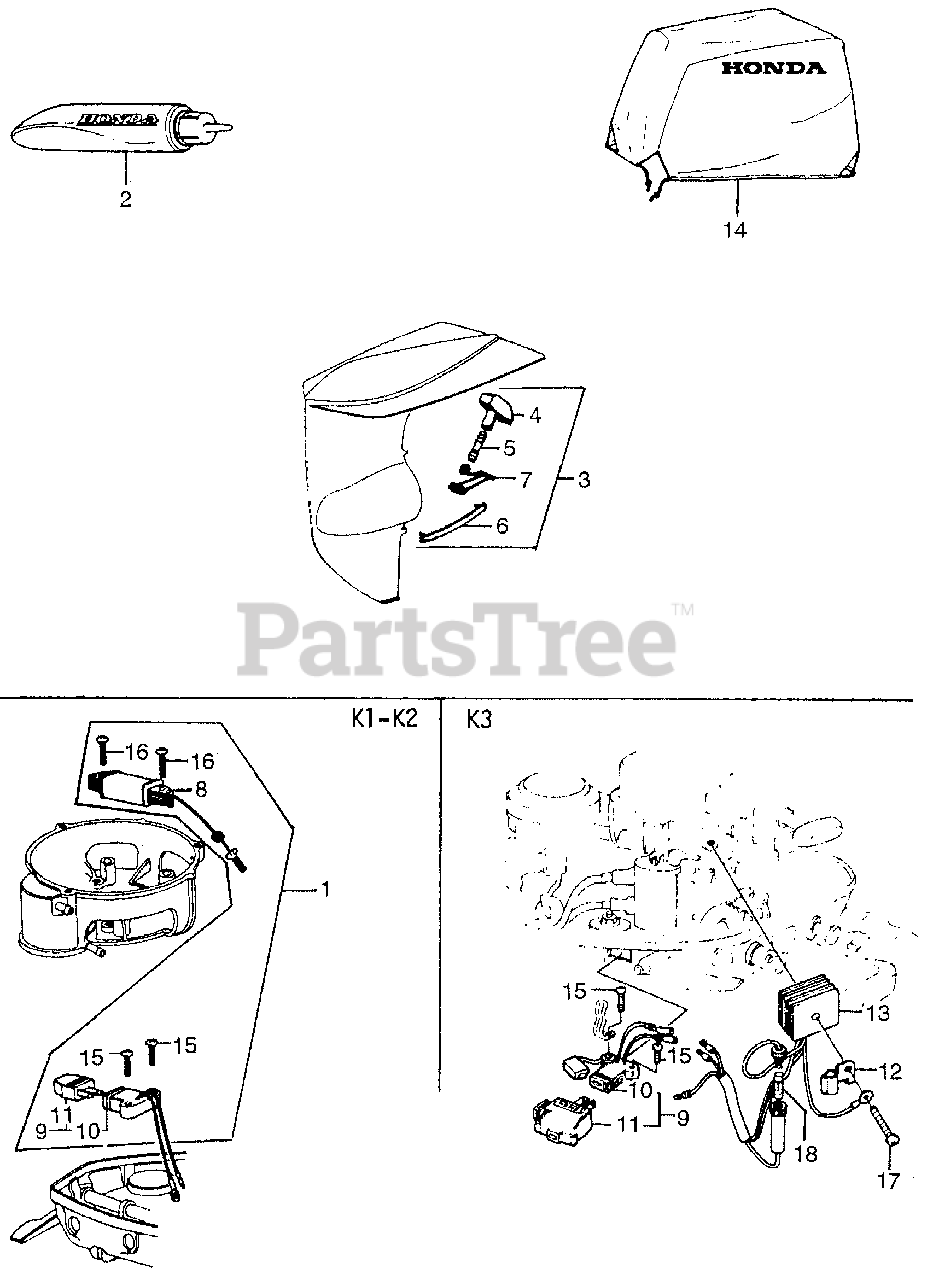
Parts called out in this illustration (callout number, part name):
2	TUBE, GEAR OIL
2	TUBE, GEAR OIL (NOT AVAILABLE)
3	MOUTH KIT, WATER
4	MOUTH, WATER
5	JOINT, HOSE (NOT AVAILABLE)
6	PLUG, WATER (NOT AVAILABLE)
7	CLIP, WATER MOUTH
8	COIL, LAMP (6V-15W)
9	RECEPTACLE ASSY., LAMP (NOT AVAILABLE)
10	RECEPTACLE
12	HOLDER, FUSE CONNECTING (NOT AVAILABLE)
13	RECTIFIER, SILICON
14	COVER, BODY (NOT AVAILABLE)
14	COVER, BODY
15	SCREW, PAN (5X22)
16	SCREW, PAN (5X25)
17	SCREW, PAN (6X35)
18	FUSE A (5A)
